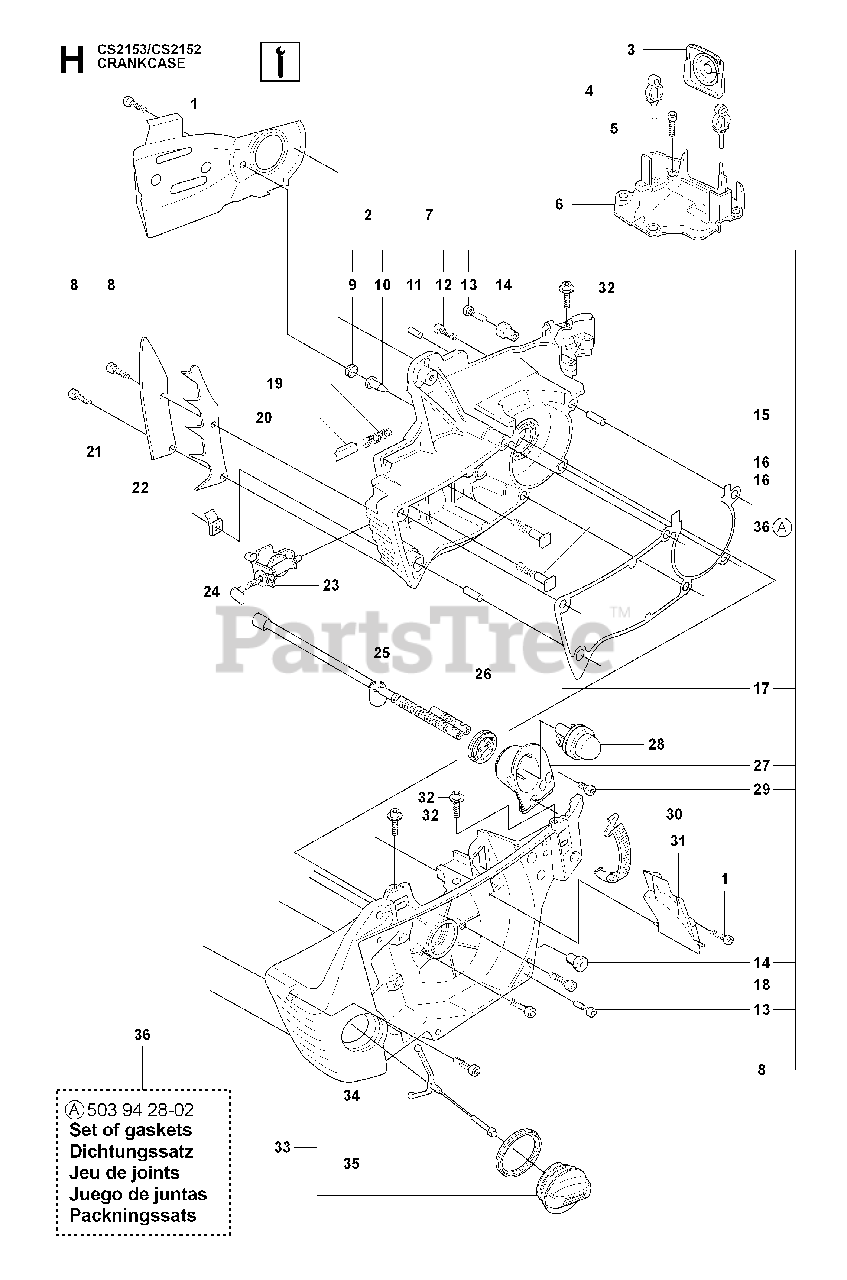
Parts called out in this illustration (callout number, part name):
2	CHAIN GUIDE PLATE
6	CARBURETTOR AREA BASE
7	CRANKCASE ASSY
9	PLUG
10	VALVE-CHECK (DUCKBILL)
14	MOVEMENT LIMITER
19	LOCK SPRING
22	FELLING DOG
23	CHAIN TENSIONER
24	CHAIN CATCHER
25	RP HOSE
28	AIR PURGE BUBBLE
29	SCREW IHSCT
31	DEFLECTOR
35	OILCAP GASKET
36	GASKET SET
